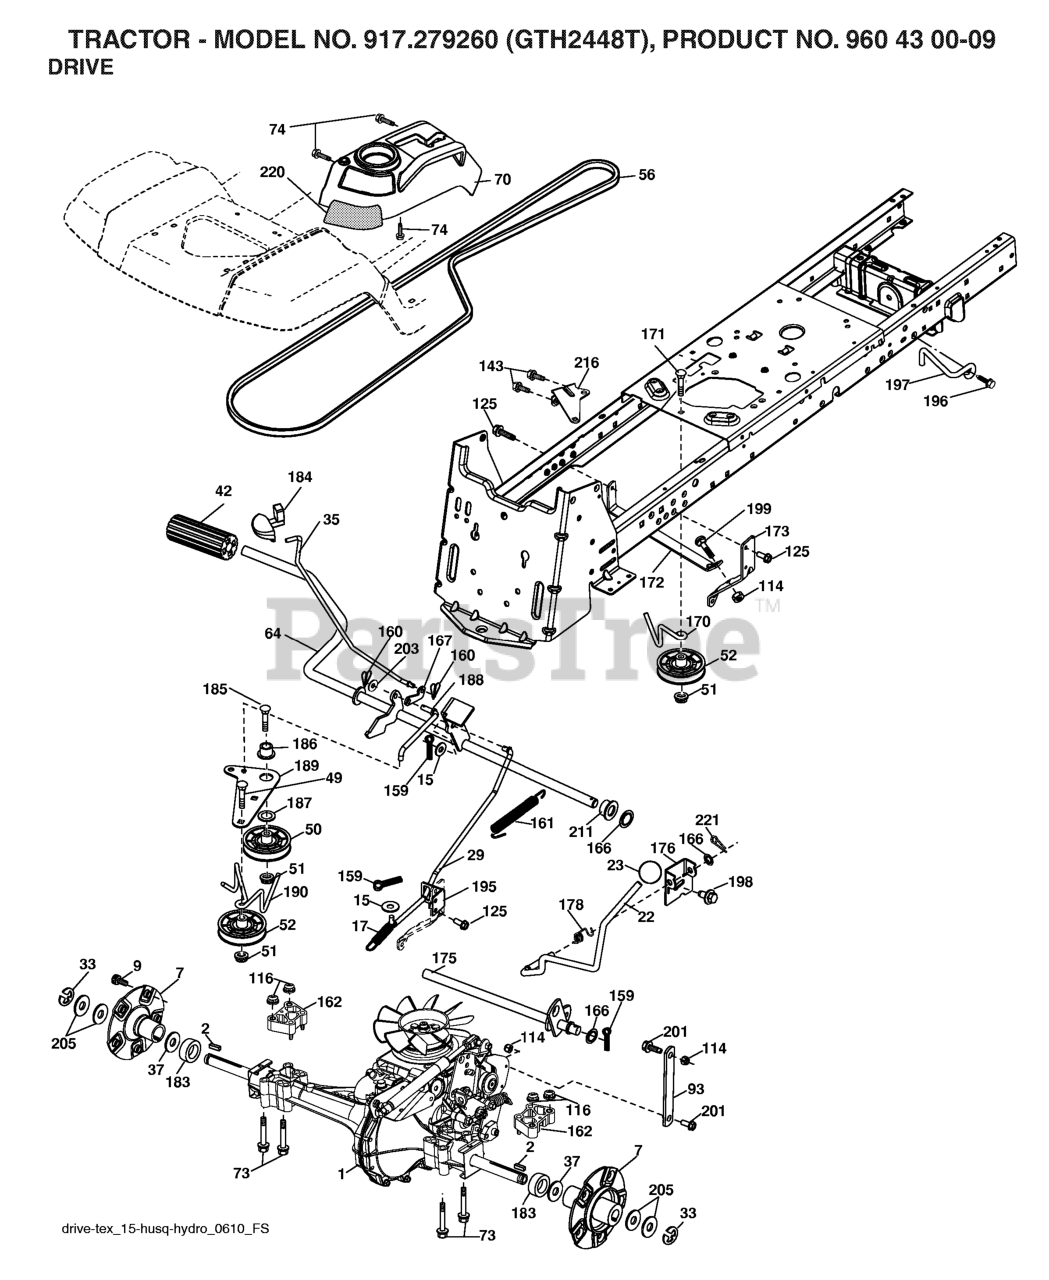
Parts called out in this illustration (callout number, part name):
2	KEY.SQUARE.187X2.500
7	HUB.ASM.WHEEL.REAR.22"
15	WASHER
17	SPRING.BRAKE.HG3000/3500
22	ROD.SHIFT.FENDER.STGT.
23	KNOB.DELUXE.(PISTOL.GRIP).BLAC
29	ROD.BRAKE.0610.PEDAL.CONTROL
35	ROD.BRAKE.PARKING.GT.H
42	PEDAL COVER T
50	IDLER.FLAT.910.OFFSET
51	NUT LOCK FLG 3/8-16 UNC
52	IDLER.V-GROOVE.910.OFFSET
64	SHAFT.ASM.PEDAL.BRAKE.
70	RP CONSOLE.ASM.HYDO.HUSQ.
73	BOLT.HEX.FLNG.5/16-18X3.75
74	SCREW.HI-LO.CONSOLE
93	LINK.SHIFT.T/A.0610.TE
114	NUT.71038.31-18.HEX.NYLOCK
116	NUT LOCK HEX FLANGE 5/16-18
125	SCREW
143	Screw 5/16-18 x 1/2 Hex, Self Tapping 5/16-18 x 1/2
159	COTTER PIN
160	RETAINER CLIP
161	SPRING.RETURN.CLUTCH.2006
162	SPACER.TRANSAXLE.18&22
166	NUT.PUSH.625.2006
167	LATCH.BRAKE.SPRING
170	KEEPER.V-IDLER.CENTER.
172	STRAP.TRQ.LH.FS.HG0510
173	STRAP.TORQUE.FS.0610.RH
175	SHAFT.ASM.SHFT.HG0510/
176	ARM.CLEVIS.ROD.SHIFT
178	SPRING.SHIFT.GT2006
183	SPACER.SPLIT.800X.350
184	HANDLE.PARKG.BRK.HUSQ X667
186	SPACER.RETAINER
187	WASHER 12/32X2X10GA
188	RP.LINK.CLUTCH.GROUND.DRIVE
189	BELLCRANK.GROUND.DRIVE.TEX.
190	KEEPER.BELLCRANK.DRIVE
195	BRKT.ROD.BRAKE.18/20/2
196	SCREW 3/8-16X1
197	BRKT.ANIT-ROTATION.CLUTCH
198	SCREW.7/16-14X7/8.FLAN
201	BOLT SHOULDER 5/16-18 UNC
203	WASHER
211	BUSHING.SHAFT.BRAKE.HAND
216	BRACKET.PULLEY.IDLER.W/TEX
220	REFLECTOR.RH.TEX GT
221	RETAINER.SPRING.CLIP.H
